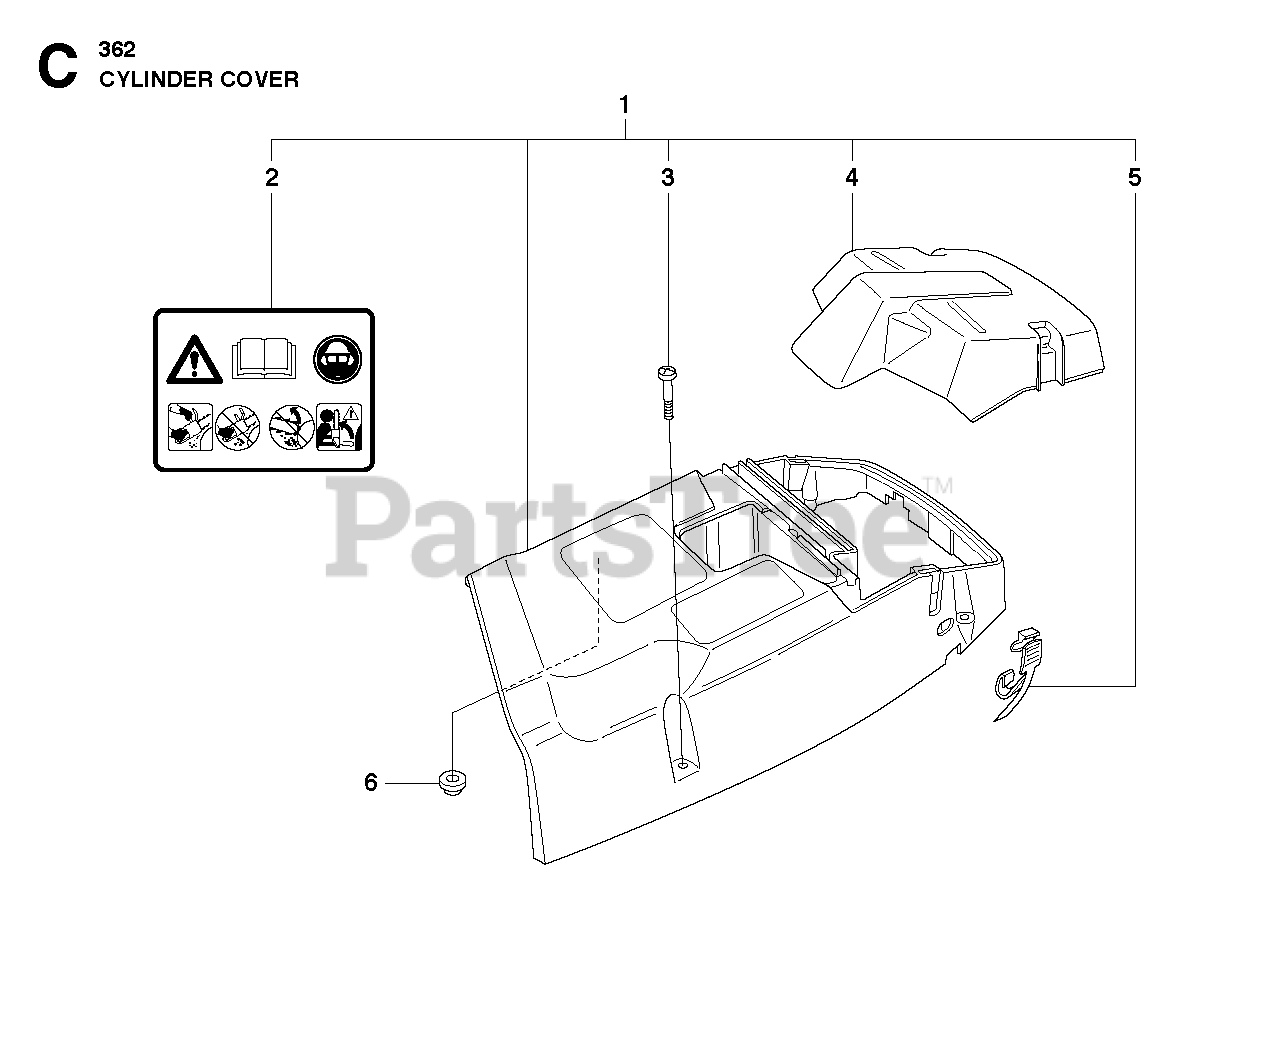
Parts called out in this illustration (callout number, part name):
1	TOP COVER
2	DECAL
3	SCREW
4	COVER
5	HOLDER
